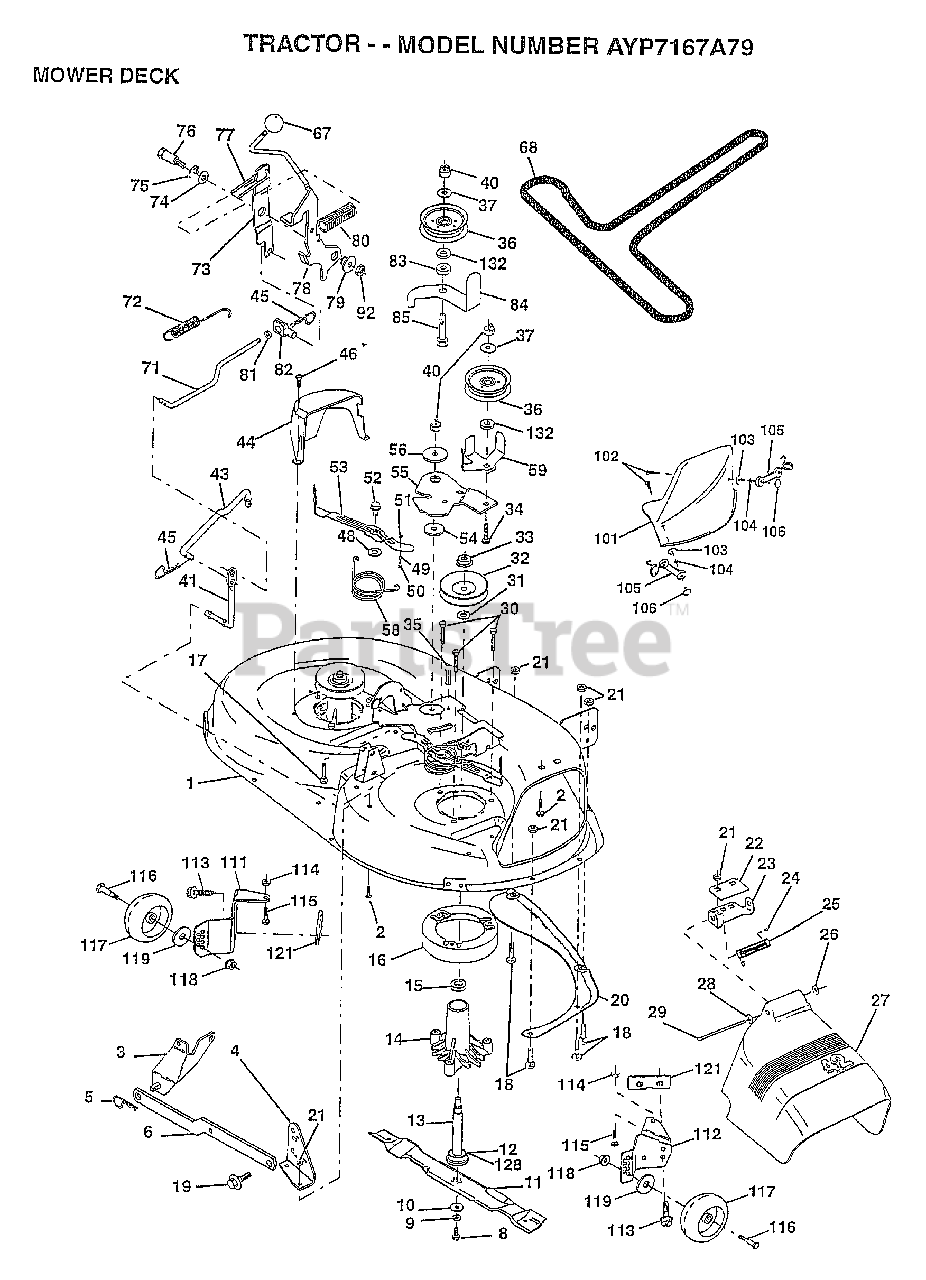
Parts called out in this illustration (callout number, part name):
1	DECK.WELD.42.
2	BOLT
3	BRKT ASM SWAY BAR
4	BRKT DECK SW BAR
8	BLADE BOLT
10	WASHER.HARD.BLADE
11	"BLADE.42"" MULCHER"
12	BEARING.BALL
14	HSG ASM MANDREL
15	BEARING
16	STRIPPER RND MWR
17	BOLT RDHD 3/8-16
18	BOLT
19	BOLT SHD 5/16-18
22	STIFFENER BRKT
23	DEFLECTOR BRKT
24	CAP-SLEEVE LT
25	SPRING TORSION
26	NUT PUSH M
27	DEFLECTOR.SHIELD
28	WASHER
29	HINGE ROD
31	WASHER
32	PULLEY.MANDREL.42
34	BOLT
35	XMAS TREE FASTNER
36	FLAT IDLER PULLEY
37	WASHER
41	PIVOT ROD
43	ROD CLUTCH W/NIBS
44	GUARD MAND LH BLK
45	RETAINER M
46	SCREW.1/4-20X5/8
48	HARD SMALL WASHER
49	ROLLER ASM-CAM
50	SHOULDER BOLT
51	LOCKNUT
52	BOLT.SHLD.5/16-18
54	HARDENED WASHER
55	ARM-IDLER
56	SPACER RETAINER
58	SPRING TORSN BRAK
59	GUARD IDLER TUV
67	KNOB T(3/8 HOLE)
68	BELT.V.T-PATH
71	ROD CLUTCH 38/42
72	RETURN SPRING
73	CLUTCH ARM SECOND
74	WASHER
75	RING
76	SHOULDER BOLT
77	SPRING KEEPER
78	LEVER ASM-CLUTCH
79	BUSHING
80	SPRING.CLUTCH.MWR
81	NUT
82	TRUNION ADJ
83	WASHER
84	"KEEPER-BELT,FIXED"
85	BOLT RDHD 3/8-16
92	NUT
101	"COVER.MULCH.42"""
102	SCREW
103	WASHER #10
104	LOCKWASHER
106	WELDNUT
111	BRACKET.GWHL.LH.
112	BRACKET.GWHL.RH.
113	SCREW
116	BOLT.SHOULDER
117	WHEEL GAGE DONUT
118	LOCKNUT
119	WASHER
121	BRACKET.EXTRD.GWL
128	WASHER.FELT.
132	WASHER GT
